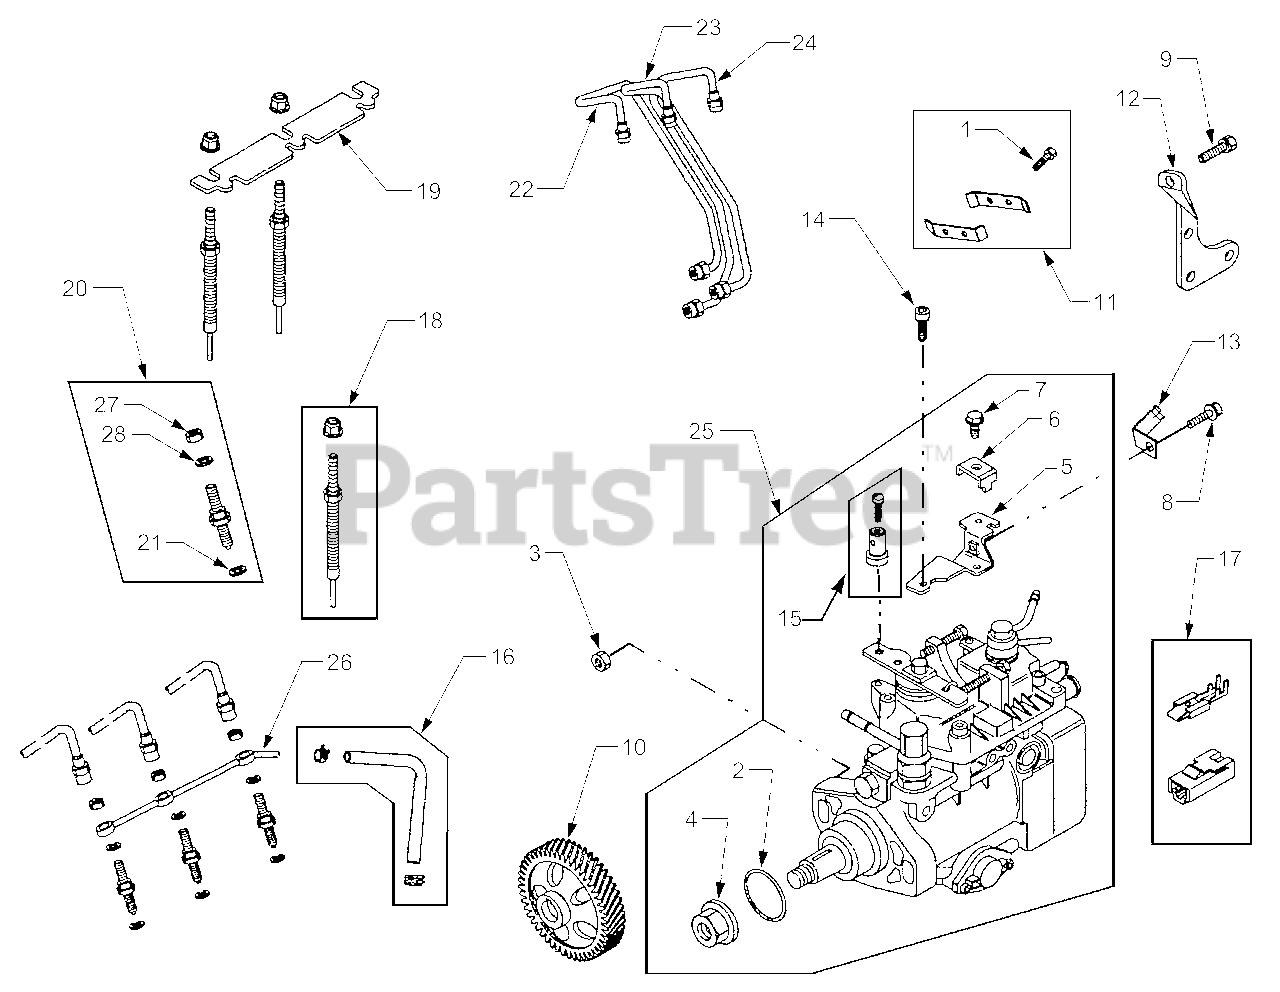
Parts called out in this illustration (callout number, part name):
1	Screw, Hex, 6mm
2	Seal, O-Ring
3	Nut, Hex Metric
4	Nut, Hex Metric
5	Bracket, Casing Clamp
6	Clamp, Casing
7	Screw, Casing Clamp
8	Screw, Support Bracket
9	Screw, Support Bracket
10	Gear, Drive
12	Bracket, Support
13	Bracket, Support
14	Screw, Casing Clamp Bracket
15	Clamp, Swivel
16	Hose/Clamp Ass'y., Fuel Return
17	Connector, Injection Pump
18	Plug, Glow
19	Strap, Glow Plug
20	Nozzle, Injector
21	Seat, Injector
22	Pipe, Injector #1
23	Pipe, Injector #2
24	Pipe, Injector #3
25	Pump, Injection
26	Pipe, Fuel Return
27	Nut, Hex Injector Nozzle
28	Washer, Injector Nozzle
